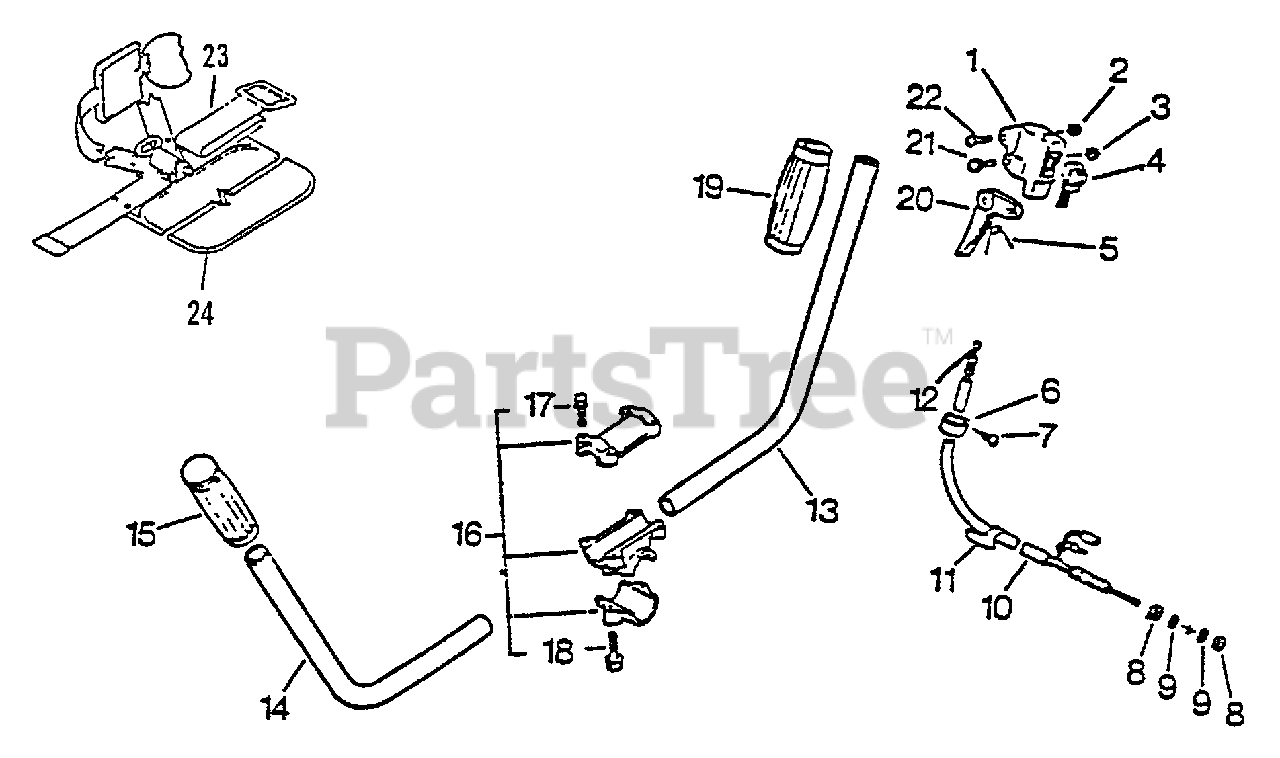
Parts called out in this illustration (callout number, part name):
1	BRACKET, THROTTLE
2	NUT, LOCK M5
3	NUT M5
4	IGNITION SWITCH ASSY
7	SCREW 5×10
9	WASHER 6.5×11.5×0.8
12	CABLE, THROTTLE
14	HANDLE, LEFT
15	GRIP, HANDLE
16	HANDLE BRACKET KIT
17	BOLT - 5×25
18	BOLT - 6×30
20	TRIGGER, THROTTLE
21	SCREW 5×25
23	PAD, HIP
24	SHOULDER STRAP ASSY
